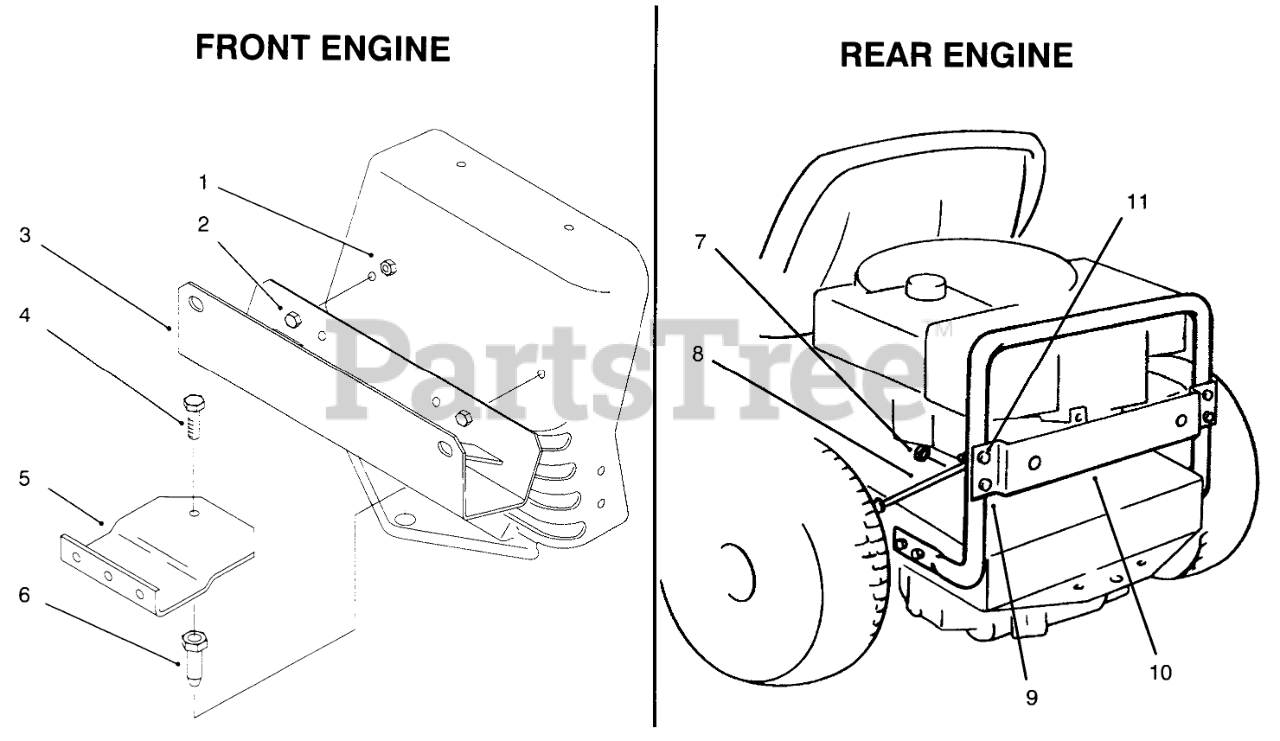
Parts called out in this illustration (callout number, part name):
1	NUT-LOCK, NI
2	SCREW-HH
3	Bracket-Channel
4	SCREW-HH
5	Bracket-Bagger Mounting
6	PIN-MOUNTING, LOWER
7	NUT-LOCK, NI
8	BAGGING KIT BRACE
9	SCREW-HH
10	Plate-Bagging Kit
11	SCREW-HH
